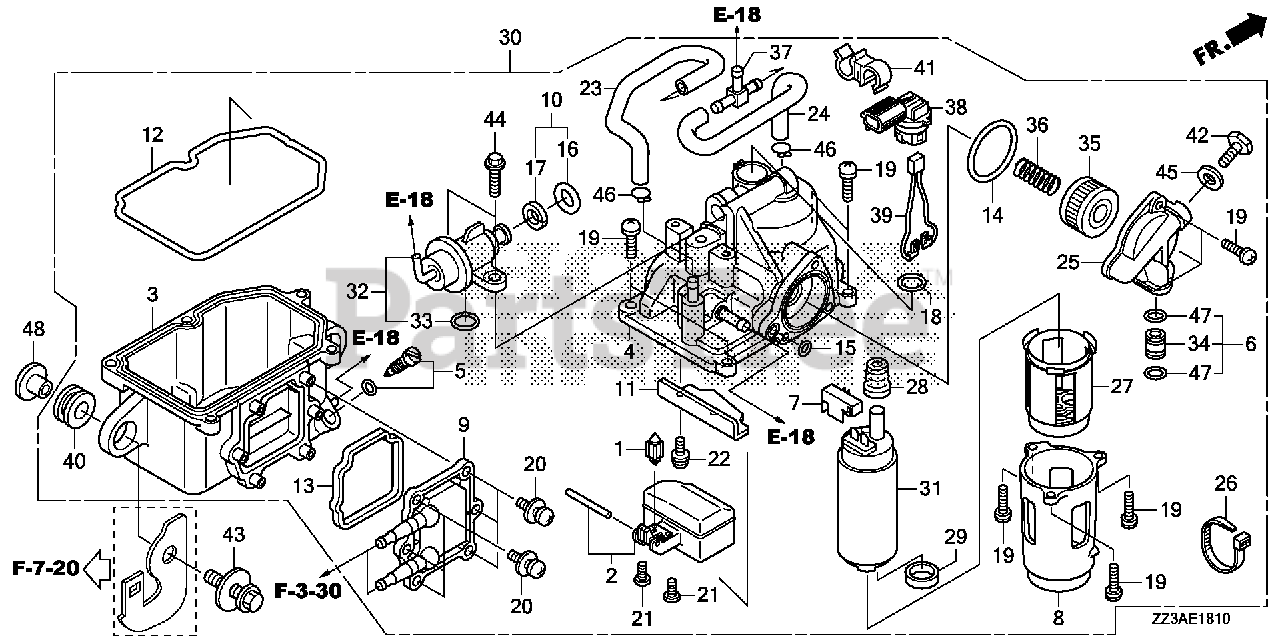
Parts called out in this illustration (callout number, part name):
1	VALVE SET, FLOAT
5	SCREW SET, DRAIN
9	COVER, WATER JACKET
17	RING, BACK-UP
19	SCREW-WASHER
20	SCREW-WASHER
21	SCREW, PAN
22	SCREW, WASHER
23	TUBE A, AIR VENT
24	TUBE B, AIR VENT
28	INSULATOR
30	SEPARATOR ASSY., VAPOR
31	PUMP UNIT, FUEL (MSDS)
32	REGULATOR ASSY., PRESSURE
33	O-RING, PRESSURE REGULATOR
34	JOINT, FUEL PIPE
35	SCREEN, FUEL STRAINER
36	SPRING, COMPRESSION
37	PIPE, THREE WAY JOINT
40	GROMMET, CASE (LOWER)
41	CLIP, R. BRAKE WIRE
42	BOLT, SEALING (6MM)
43	BOLT-WASHER (6X25)
44	BOLT, FLANGE (6X14)
45	WASHER, SEALING (6MM)
46	CLIP, TUBE (B10)
47	O-RING (7.8X1.9) (ARAI)
48	COLLAR, MODULE IGNITION CONTROL CASE (CDI)
